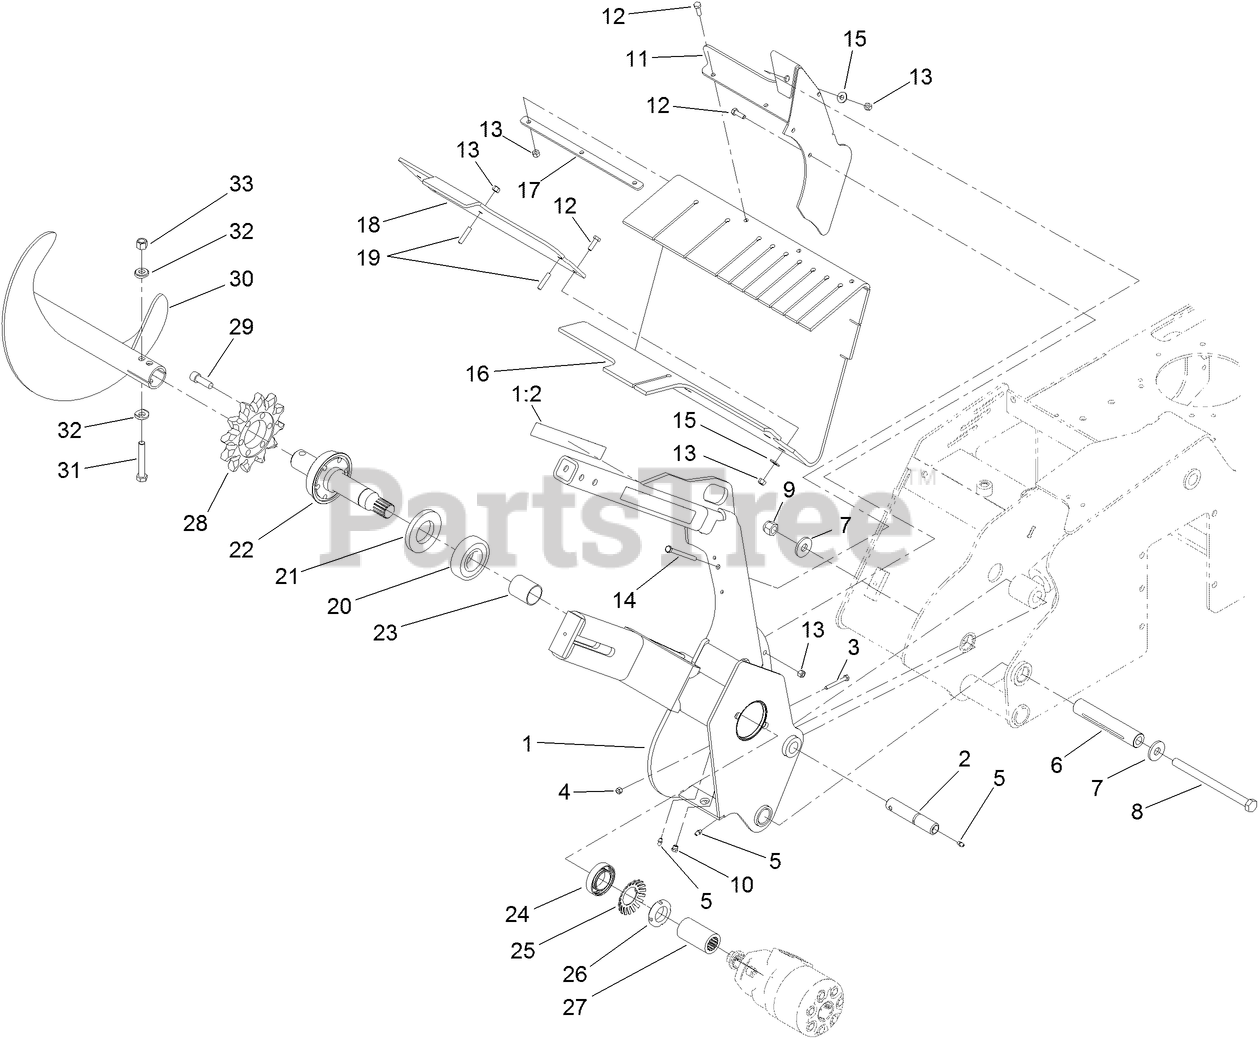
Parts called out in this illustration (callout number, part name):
1	TRENCHER HEAD ASM
1:2	DECAL-DANGER
2	PIN-PIVOT
3	SCREW-HH
4	NUT-LOCK, NI
5	FITTING-GREASE
6	SPACER-PIVOT
7	WASHER-HARDENED
8	BOLT-HH
9	NUT-LOCK, NI
10	FITTING-LUBE
11	BRACKET-SHIELD
12	SCREW-HH
13	NUT-LOCK, NI
14	SCREW-HH
15	WASHER-FLAT
16	SHIELD-DIRT
17	PLATE-STRAP, SHIELD
18	BAR-CLAMP
19	SCREW-HSH
20	BEARING-BALL
21	SEAL-GREASE
22	SHAFT-TRENCHER
23	SPACER
24	BEARING-BALL
25	LOCKWASHER-BEARING
26	LOCKNUT-BEARING
27	COLLAR-SPLINED
28	SPROCKET-TRENCHER
29	SCREW-HSH
30	AUGER-TRENCHER
31	SCREW-HH
32	WASHER-SADDLE
33	NUT-LOCK, NI
